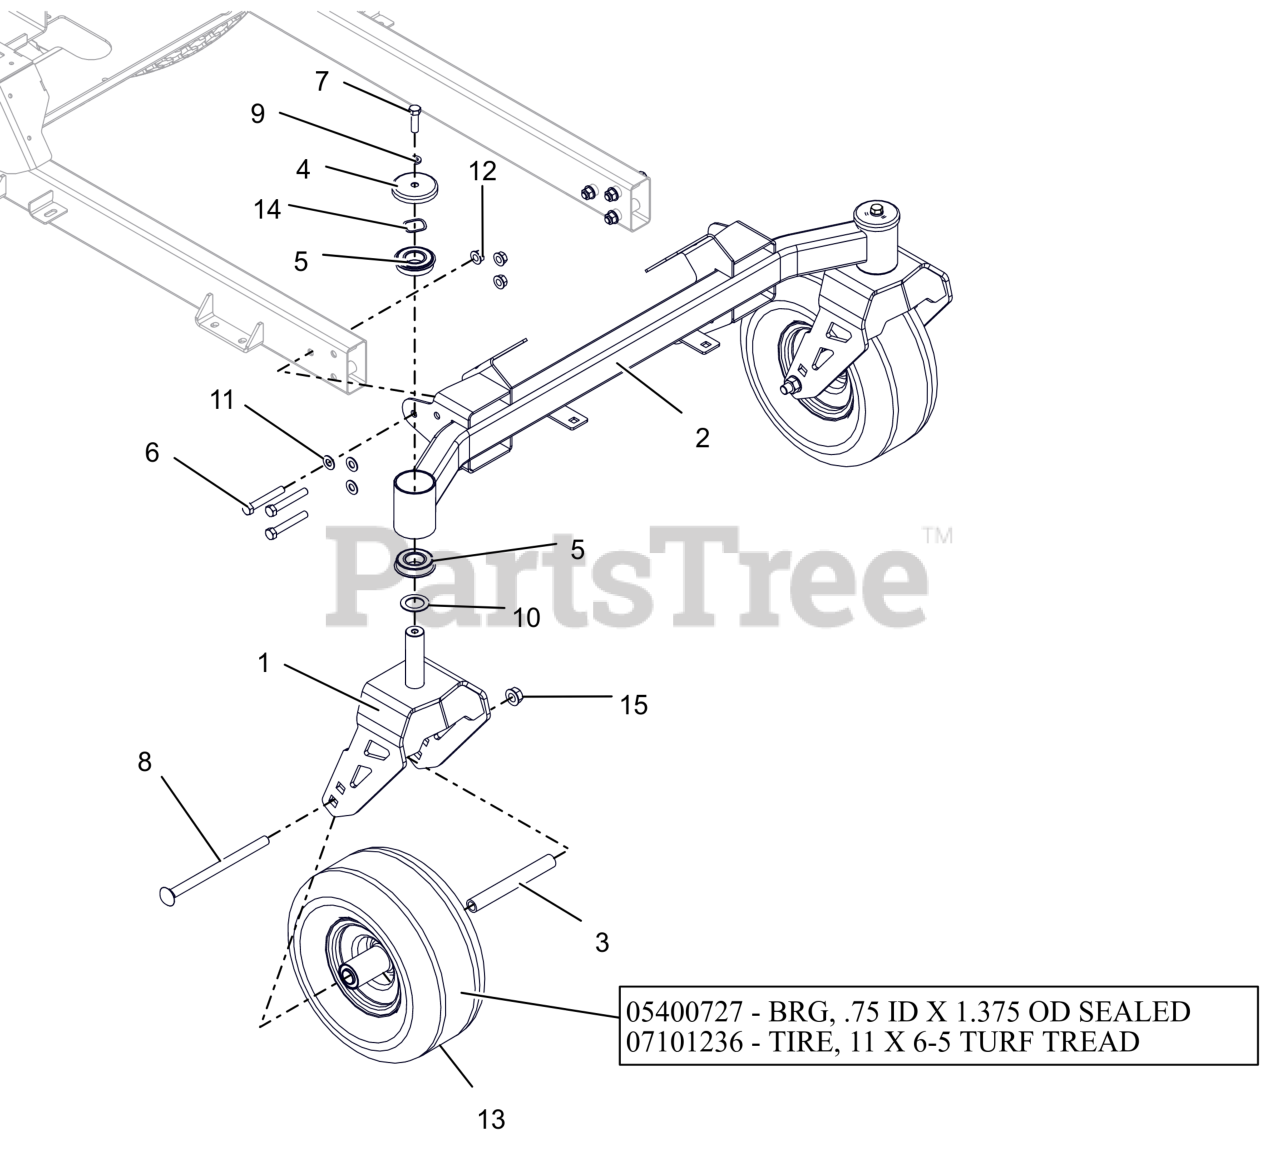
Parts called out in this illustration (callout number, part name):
1	WMT-CASTER FORK-XL
2	WMT-FRONT AXLE-X/XL
3	SPACER, FRONT WHEEL (WIDE 6.0)
4	SHIELD, AXLE BEARING
5	BEARING, BALL -2.000 OD X 1.000 ID X .5625 W/RING
6	BLT, HEX .38-16X2.50 G8 ZCC
7	BLT, HEX .38-16X1.25 G5 ZCC
8	BLT, RHSN .50-13X7.50 G5 ZCC
9	WSHR,LK-REG .375X.094 ZCC
10	WSHR-HRD-THRS 1.007X1.542X.062
11	WSHR,FLT-HRD.406X.812X.055 MZC
12	NUT-LK-TOP-FLG .375-16 GG ZCC
13	TIRE/WHEEL ASSY, 11X6-5
13	BRG, .75 ID X 1.375 OD SEALED
13	TIRE, 11X6-5 TURF TREAD
14	WSHR-WAVE 1.0X1.25X.028 .145FH
15	NUT-LK-TOP-FLG .500-13 GF ZCC
